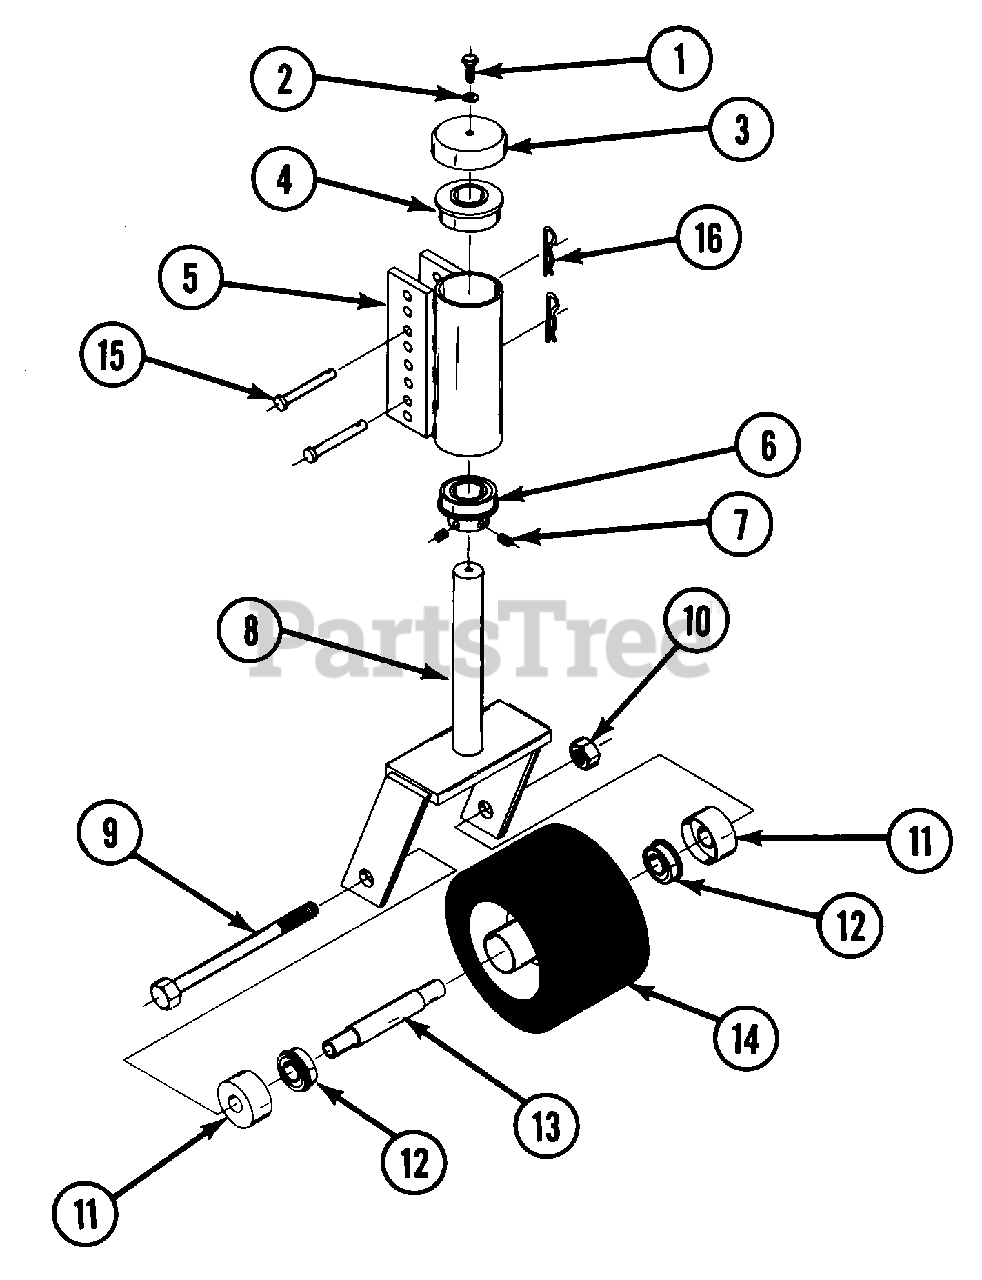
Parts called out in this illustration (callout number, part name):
1	CAPSCREW, HEX, 1/4-20 X 5/8, GR. 5
2	LOCKWASHER, 1/4 SPLIT SPRING
3	CAP, BEARING
4	BEARINGS 1" BORE
5	CASTER TUBE WELDMENT
6	BEARINGS 1" BORE
7	SETSCREW 1/4-28 X 5/16 NYLOCK
8	CASTER YOKE WELDMENT
9	CAPSCREW, 1/2-13 X 5-1/2, GR. 5
10	NUT, HEX 1/2-13 STOVER
11	SHIELD, BEARING
12	BEARINGS 5/8 I.D. X 1-3/8 O.D.
13	SPACER, BEARING
14	WHEEL ASSEMBLY RIM, TIRE & BEARINGS
15	PIN, CLEVIS 3/8 X 2
16	PIN, HAIR SPRING X 1-9/16
